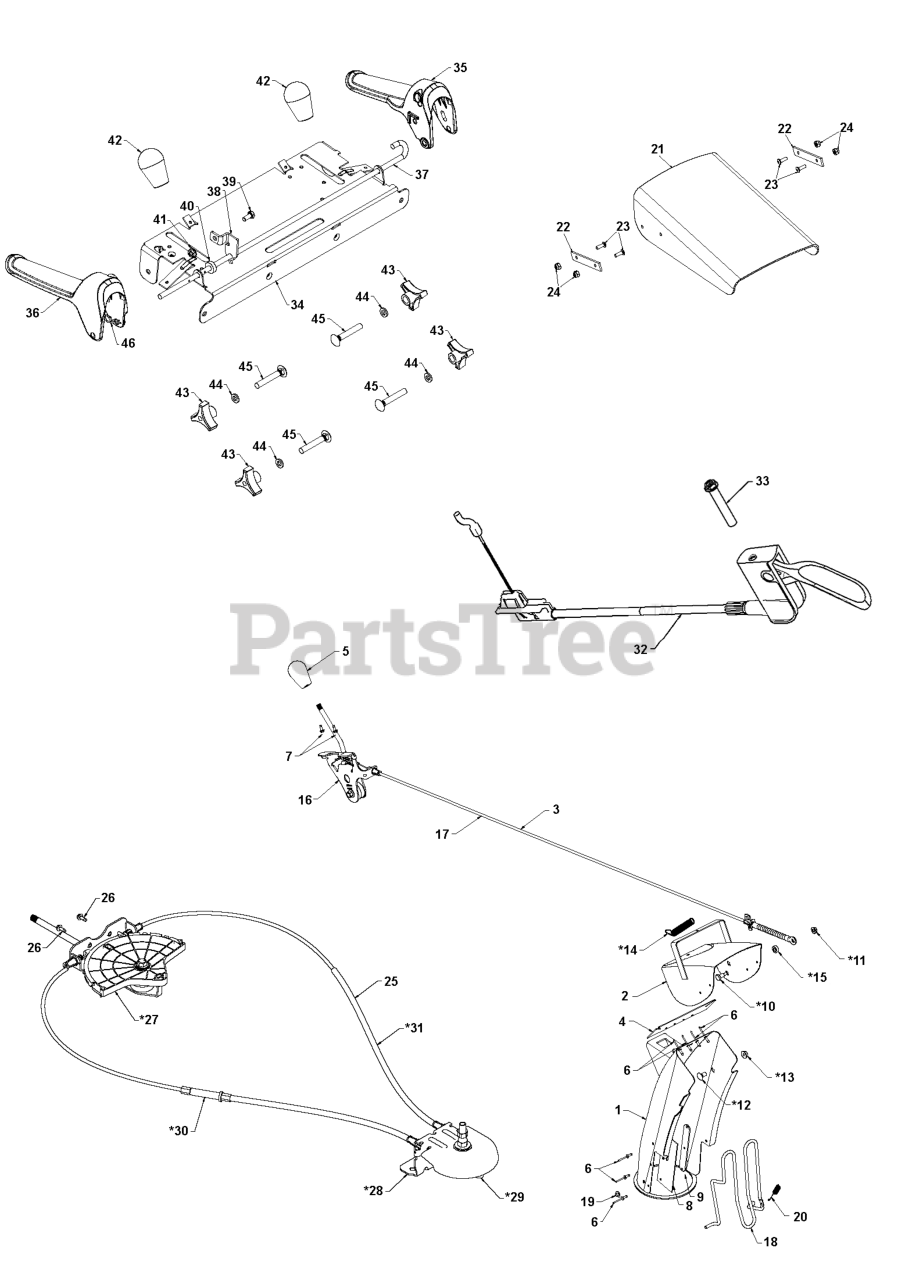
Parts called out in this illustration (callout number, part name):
1	ASM.CHUTE/DEFLECTOR.668
1	CHUTE.WELDMENT.SNOW.ORANGE
2	DEFLECTOR.WELDMENT.PNT.ORANGE
3	CONTROL.ASM.DEFLEC.BLK.BOWDEN
4	SEAL.DEFLECTOR
5	KNOB.OVERMOLD.DS.HUSQVARNA/BLK
6	RIVET BLIND
8	SHIELD.SNOW.CHUTE
9	STRAP.SHEILD.RETAINER
16	RP CNTRL.HEAD.ASSEM.DEFLECTOR
17	RP CABLE.DEFLECTOR.BOWDEN
17	RP CABLE.DEFLECTOR.CONTRL.BOWD
18	ROD.GUARD.CHUTE (2 2)
19	NUT
20	SPRING.CHUTE.GUARD
21	SHIELD.DEFLECTOR.BLACK.SNOW
22	DEFLECTOR SHIELD STRAP
23	SCREW.MACHINE.8-32 X 1/2-BLK
24	NUT.HEX.NYLOCK
25	LEVER/CABLE.ASM.ROTATOR
32	CABLE.ASM.HYDROII.BLK/BLK
34	PANEL.CONTROL.SNOW.BLACK
35	LEVER.CONTROL.LH.PL.BLACK
36	LEVER.CONTROL.RH.PL.BLACK
37	BAIL.CONTROL.INTERLOCK.SNOW
38	BRACKET.ARM.IMPELLER.ROD.YZ
39	BOLT
40	SPACER.CONTROL.LEVER
42	KNOB.OVERMOLD.DS.HUSQVARNA/BLK
43	KNOB.HANDLE.3/8.TRI-POINT.BLAC
44	WASHER
45	BOLT 3/8-16 X 2-1/4
46	SPRING RETAINER
